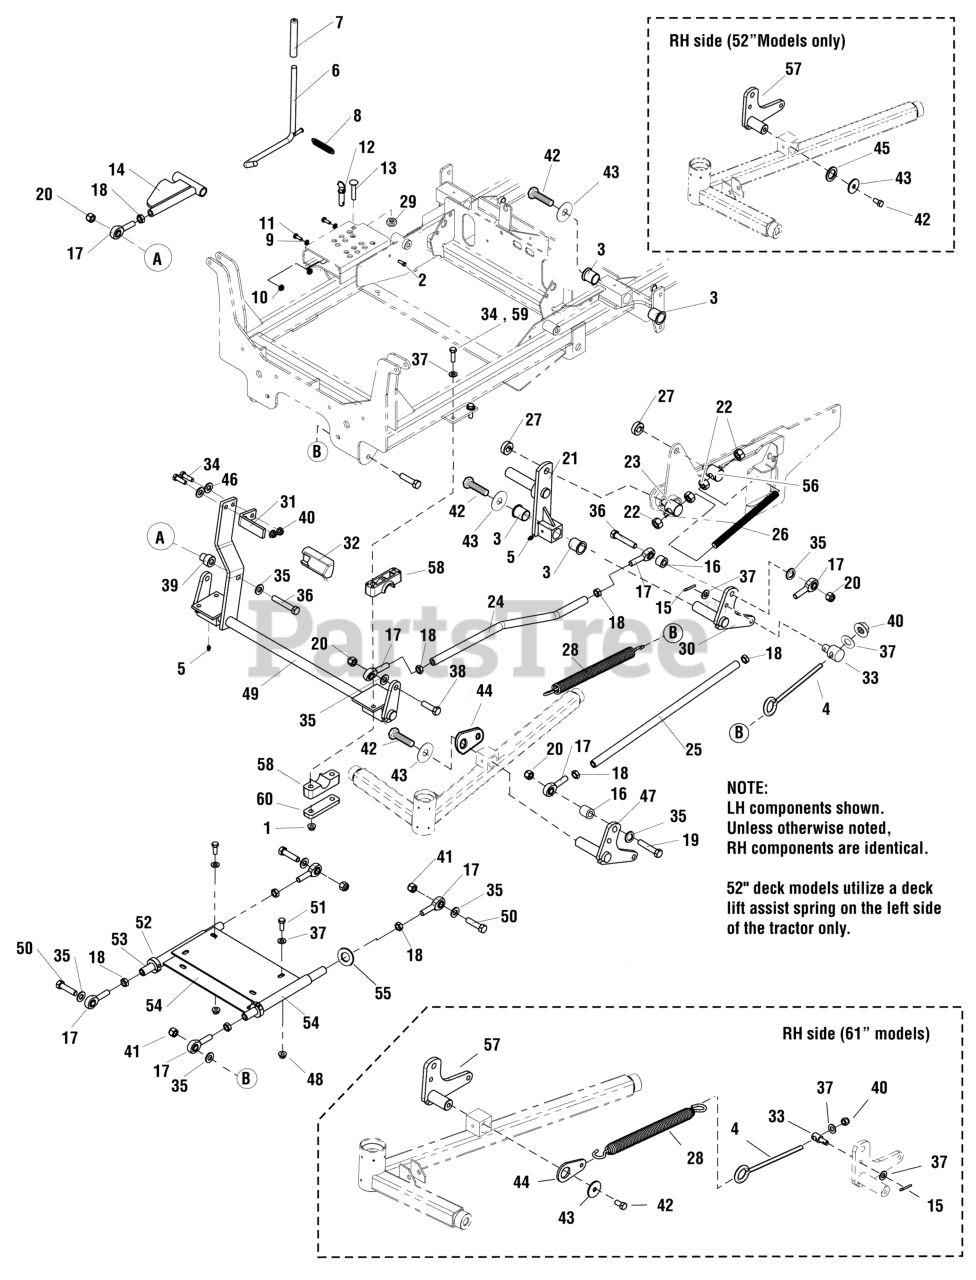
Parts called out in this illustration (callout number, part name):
1	NUT, 3/8-16 HEX NYLOCK FLANGE
2	PIN, CLEVIS, 1/4 X 7/8, PLATED
3	BUSHING, 1.00 X 1.13 X 1.38, PLASTIC
4	* EYEBOLT, 3/2-16 X 8", 1" EYE
5	GREASE FITTING, 1/4-28 STRAIGHT
6	WELD, ROD DECK LIFT - BLK
7	GRIP, FOAM
8	SPRING, EXTENSION
9	WASHER, 1/4 SAE
10	NUT, 1/4-20 HEX SERR. FLANGE
11	BOLT, 1/4-20 X 3/4" GD5 YZ
12	PIN, HITCH, 1/2 X 2.00 OAL, YP
13	BOLT, 3/8-16 X 2", CARRIAGE
14	WELD, DECK ADJUST LINK - RED
15	* PIN, COTTER, 1/8" X 3/4
16	SPACER, .52 X 1.00 X .75
17	BALL JOINT, 1/2-20, MALE
18	NUT, 1/2-20 HEX JAM
19	BOLT, 1/2-13 X 2-3/4 GD5 CZ
20	NUT, 1/2-13 HEX NYLON LOCK
22	NUT, 5/8-11 HEX
23	PIVOT, SPRING ROD
24	ROD, DECK LIFT BENT
25	ROD, DECK LIFT, OUTER
26	ROD, 5/8-11 X 9.00
27	COLLAR, 5/8" SPLIT
28	* SPRING, DECK LIFT ASSIST
29	NUT, 3/8-16 HEX SIDE LOCK
31	PEDAL, FOOT - BLK
32	PEDAL, Rubber
33	* ADJUSTER, DECK HANGER
34	BOLT, 3/8-16 X 1-1/4" GD5 CZ
35	WASHER, 1/2" SAE
36	BOLT, 1/2-13 X 3-1/2, HEX HD, GD5, CZ (SV)
37	WASHER, 3/8 SAE
38	BOLT, 1/2-13 X 1-3/4 GD5 CZ
39	ADAPTER, CASTER AXLE, CZ
40	NUT, 3/8-16 HEX NYLON LOCK
41	NUT, Hex, Nylon Lock, 1/2-20
42	BOLT, 3/8-16 X 3/4, PLT W/PATCH
43	WASHER, .390 X 1.50 X .109, YZ
44	* MOUNT, SPRING DECK LIFT - RED
45	SHIM, 1.0 X 1.5 X 0.125
46	WASHER, 3/8" GR9 FLAT
47	WELD, PIVOT DECK LIFT - LH - RED
48	NUT, 3/8-16 HEX SERRATED FLANGE
49	WELD, DECK LIFT SHAFT - RED
50	BOLT, 1/2-20 X 1-3/4" GD8 CZ
51	BOLT, 3/8-16 X 1" GD5 CZ
52	COLLAR, 3/4" SPLIT
53	SHAFT, DECK STABILIZER
54	WELD, DECK STABILIZER - BLK
55	WASHER, 1/2 SAE
57	WELD, PIVOT DECK LIFT - RH - RED
58	PIVOT BLOCK, PLASTIC
59	BOLT, 3/8-16 X 2-3/4" GD5 CZ
60	PLATE, PIVOT BLOCK SUPPORT - BLK
